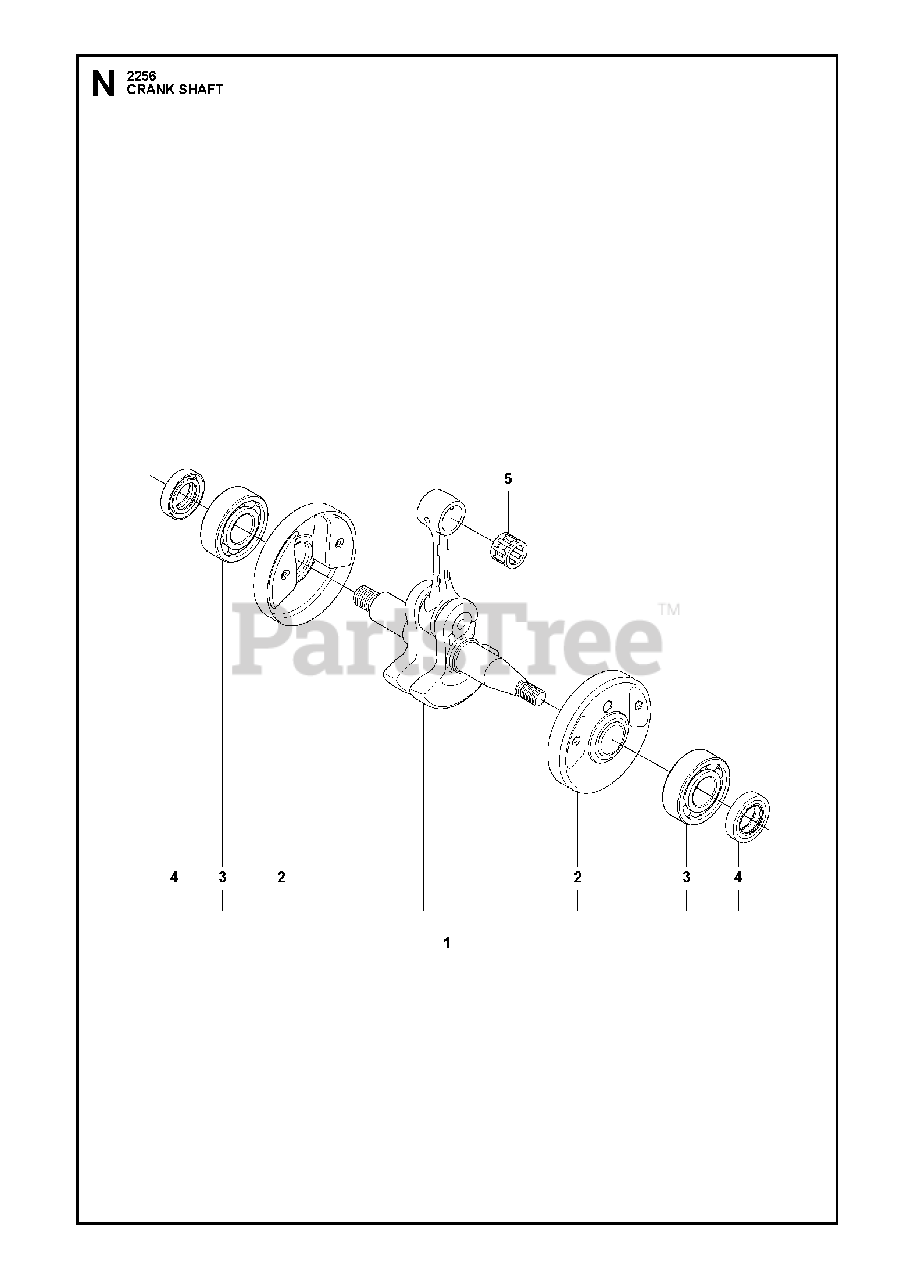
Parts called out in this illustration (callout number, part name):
1	CRANKSHAFT
2	CUP
3	BALL BEARING
4	SEALING RING
5	RP SUPPORT BUSHING
